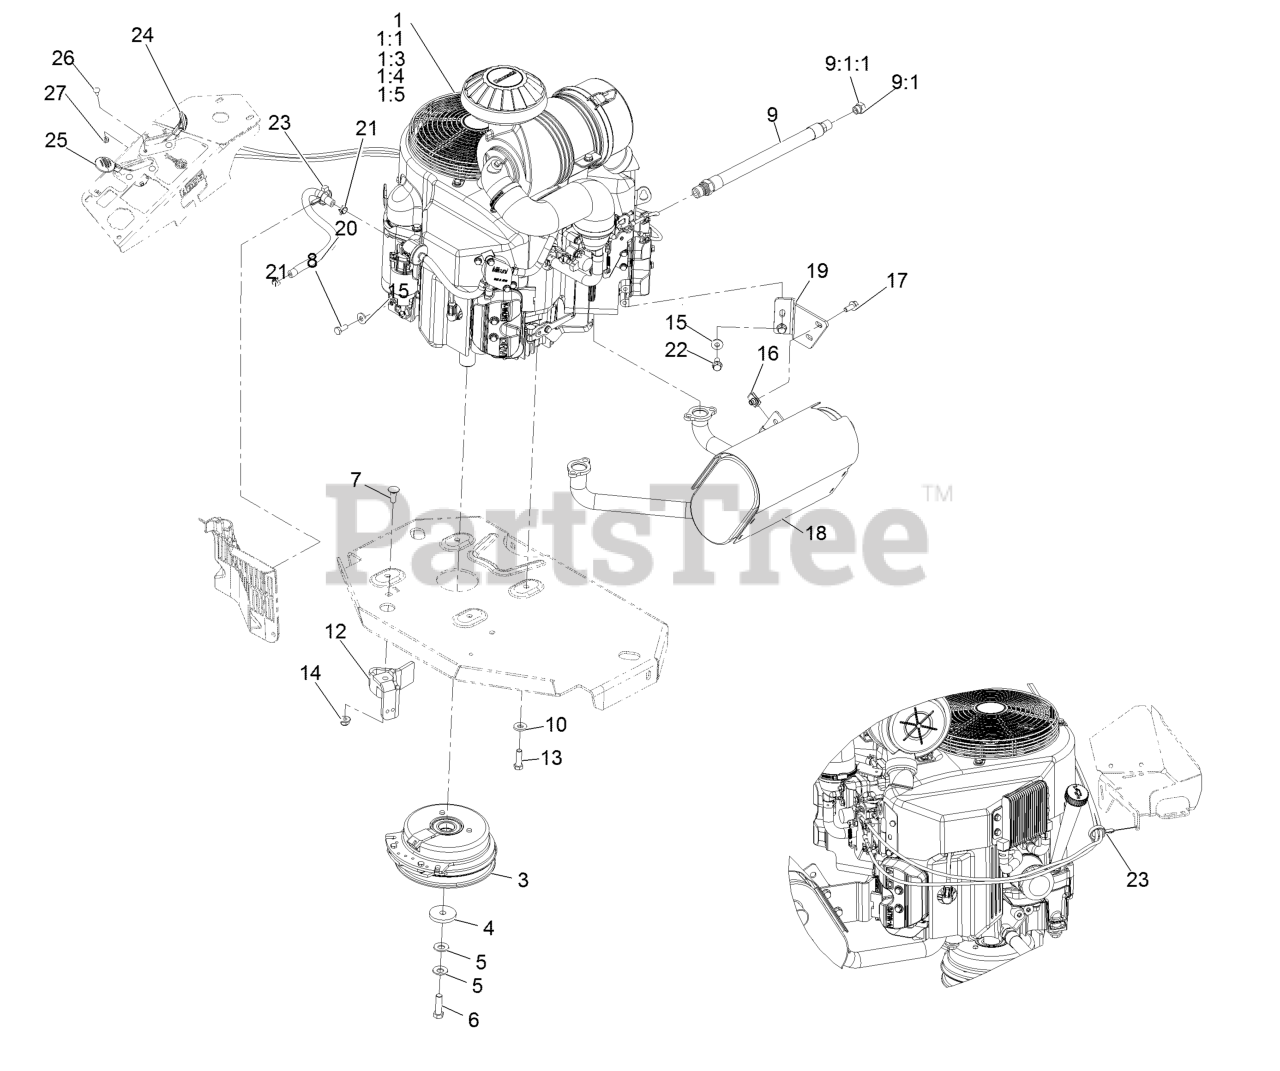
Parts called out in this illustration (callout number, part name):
1:1	Kawasaki 49065-2078 Engine Oil Filter
1:3	Kawasaki 49019-7001 Fuel Filter
1:4	Kawasaki 11013-7039 Safety Filter
1:5	Kawasaki 11013-7038 Air Filter
3	Clutch Kit
4	Washer-Clutch
5	Washer-Spring Disc 7/16
6	Screw-HH 7/16-20 X 1 1/2 W/Loctite
7	Bolt-Carriage 3/8-16 X 1
8	Screw-HH M8-1.25 X 20Mm
9	Asm-Hose Oil Drain W/Plug
9:1	Plug-W/O-Ring
9:1:1	O-Ring
10	Washer-Spring Disc 3/8
12	Clutch-Anchor
13	Screw-HH 3/8-16 X 1 1/4
14	Nut-Nyloc 3/8-16 Flg
15	Washer-Spring Disc 5/16
17	Screw-HH Flg 5/16-18 X 3/4
18	Muffler
19	Bracket-Muffler
20	Hose-Fuel Line 15"
21	Clamp-Hose
22	Screw-HH M8-1.25 X 20Mm
23	Clamp-Hose
24	ASM, Choke Cable
25	ASM,Throttle Cable
26	Bolt-Carriage #10-24 X 1/2
27	Nut-Nyloc #10-24
